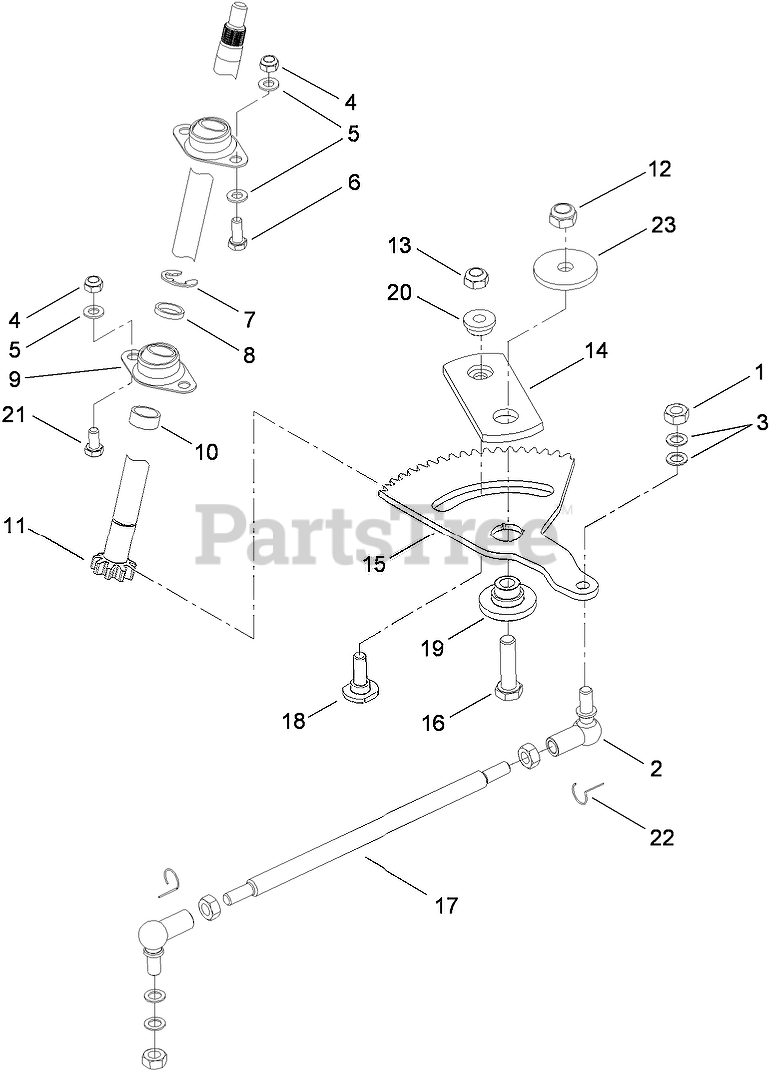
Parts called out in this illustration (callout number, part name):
1	NUT-LOCK, NI
2	JOINT-BALL, ANGLE
3	Washer
4	NUT-LOCK, NI
5	WASHER-PLAIN
6	SCREW-HH
7	CLIP-SPRING
8	SPACER-UPPER
9	BEARING-SPHERICAL
10	SPACER-LOWER
11	Shaft-Steering
12	NUT-LOCK
13	NUT-LOCK, NI
14	Plate-Steering
15	GEAR-SECTOR
16	SCREW-HH
17	LINK-DRAG
18	Bolt-Shoulder
19	Pivot-Steering
20	Bushing
21	SCREW-HH
22	Stirrups-Locking
23	WASHER
